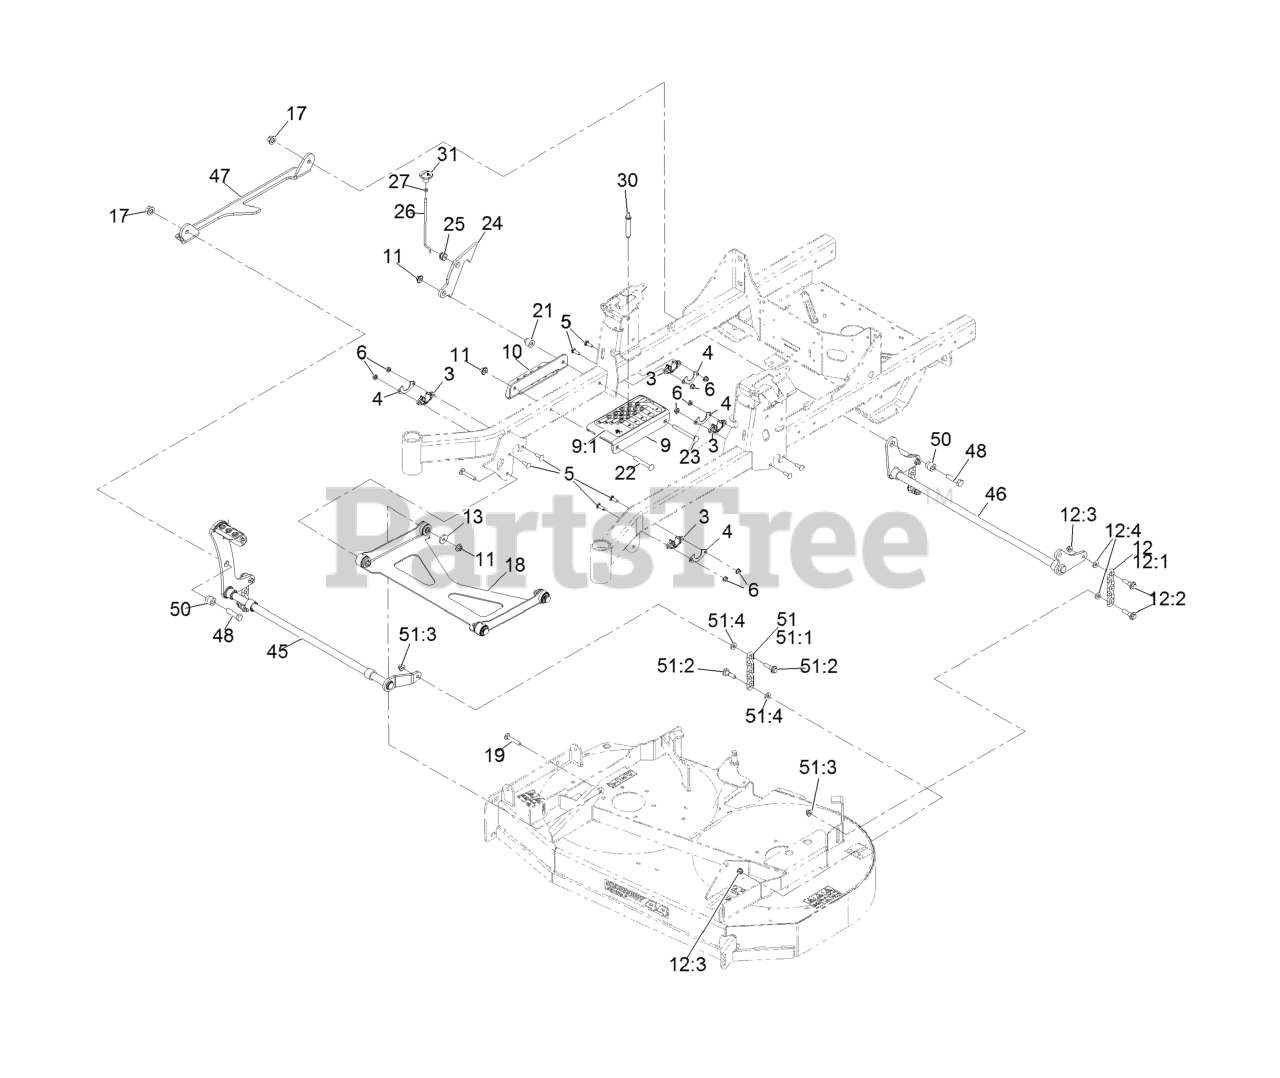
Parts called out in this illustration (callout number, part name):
3	BUSHING-FLANGE
4	GUSSET-LIFT, DECK
5	SCREW-CARR
6	NUT-HF, NI
9	BRACKET ASM
9:1	DECAL-HOC
10	ANGLE-HOC, LOWER
11	Nut-Nyloc 3/8-16 Flg
12	DECK CHAIN ASM
12:1	CHAIN-LIFT, DECK
12:2	BOLT-SHOULDER
12:3	NUT-HF, NI
17	Nut-Lock 1/2-13
18	DECK STRUT ASM
19	Bolt-Carriage 3/8-16 X 2 1/4
21	SPACER-STEPPED
22	SCREW-CARR
23	SCREW-CARR
24	PLATE-LOCK, TRANSPORT
25	GROMMET
26	ROD-LOCK, TRANSPORT
27	NUT-JAM
30	PIN-HOC
45	SHAFT-DECKLIFT FRONT
46	SHAFT-DECKLIFT REAR
47	LINK-DECKLIFT
48	SCREW-HH
50	Spacer-Stepped
51	Deck Chain ASM
51:1	CHAIN-LIFT, DECK
51:2	BOLT-SHOULDER
51:3	NUT-HF, NI
